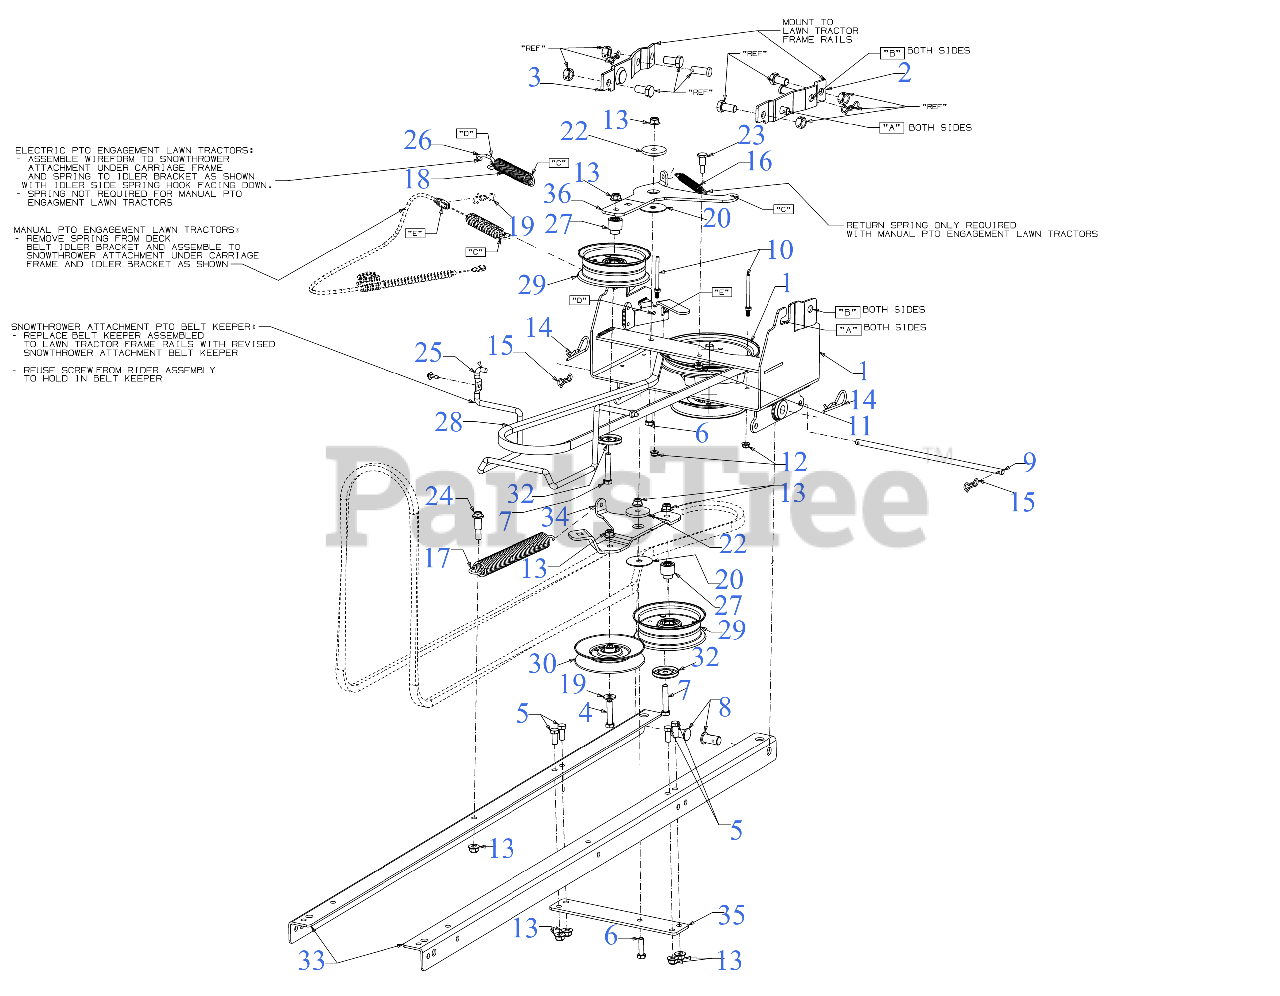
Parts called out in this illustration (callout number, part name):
1	SPINDLE ASSEMBLY
2	HANGER BRACKET (LH)
3	HANGER BRACKET (RH)
4	HEX SCREW 3/8-16 x 1.75 GR5
5	SCREW 3/8-16 x .880 GR5
6	SCREW 3/8-16 x 1.25 GR5
7	SCREW 3/8-16 x 2.0 GR5
8	CLEVIS PIN .62
9	BELT KEEPER ROD
10	BELT KEEPER .25X2.64
11	FLANGE LOCK NUT 5/16-18
12	FLANGE LOCK NUT
14	INTERNAL COTTER PIN
15	BOW TIE COTTER PIN
16	EXTENSION SPRING
17	EXTENSION SPRING
18	SPRING KIT-IDLER
19	FLAT WASHER .385X.870X.090
20	THRUST WASHER
22	SHOULDER SPACER
23	SHOULDER SCREW
24	SHOULDER SCREW .50X.925
25	BELT KEEPER ROD
26	EXTENSION SPRING HOOK
27	SHOULDER SPACER
28	V-BELT B SEC x 68.2
29	IDLER PULLEY 4.50" DIA
30	IDLER PULLEY 5.06 DIA
32	IDLER PULLEY CAP
33	UNDER CARRIAGE RAIL(POWDER BLACK)
34	IDLER BRACKET PIVOT (POWDER BLACK)
35	IDLER SUPPORT BRACKET (POWDER BLACK)
